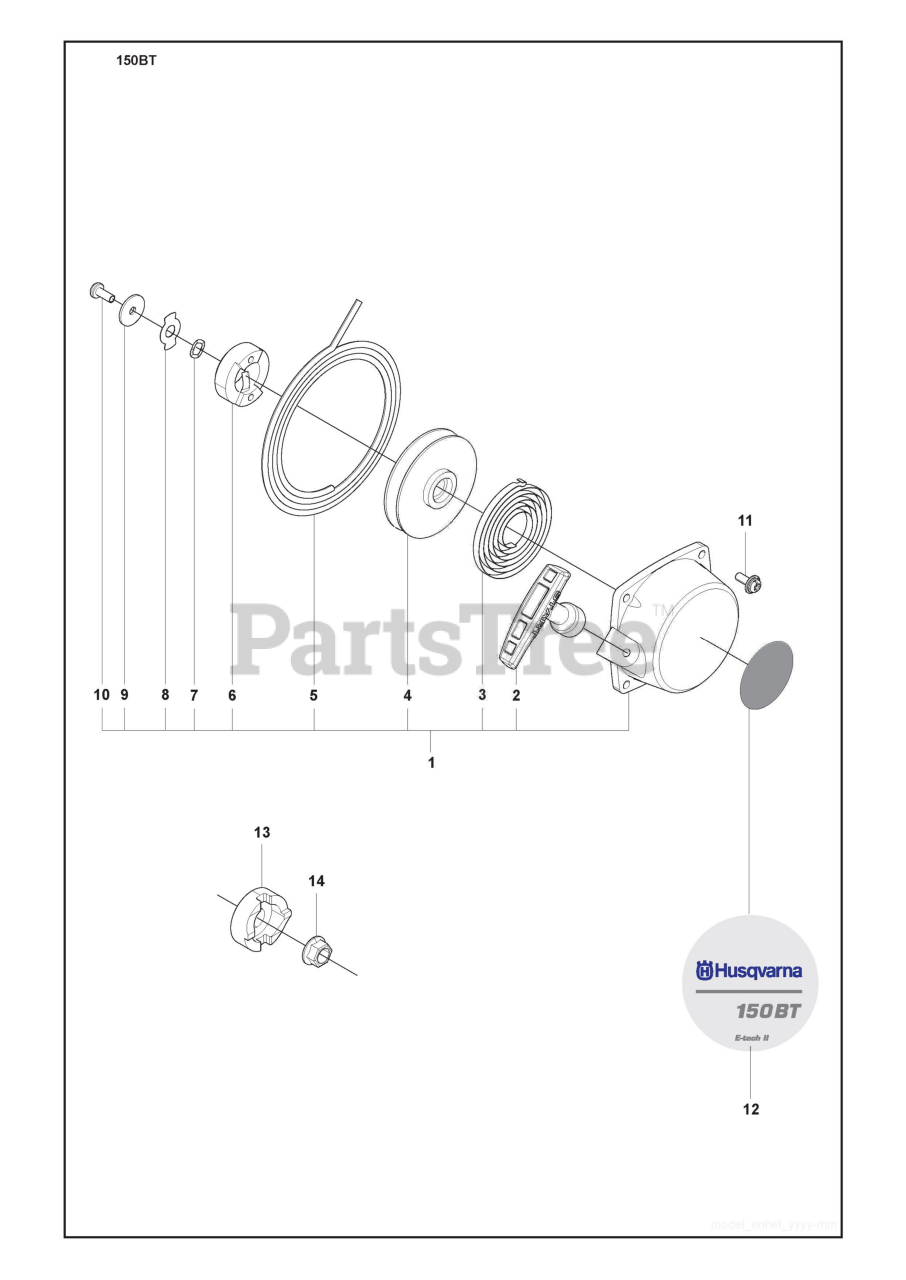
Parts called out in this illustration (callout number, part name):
1	STARTER ASSY
4	STARTER PULLEY
6	STARTER PAWL
8	RETAINER
9	WASHER
12	LABEL RECOIL
13	STARTER PAWL
14	NUT
